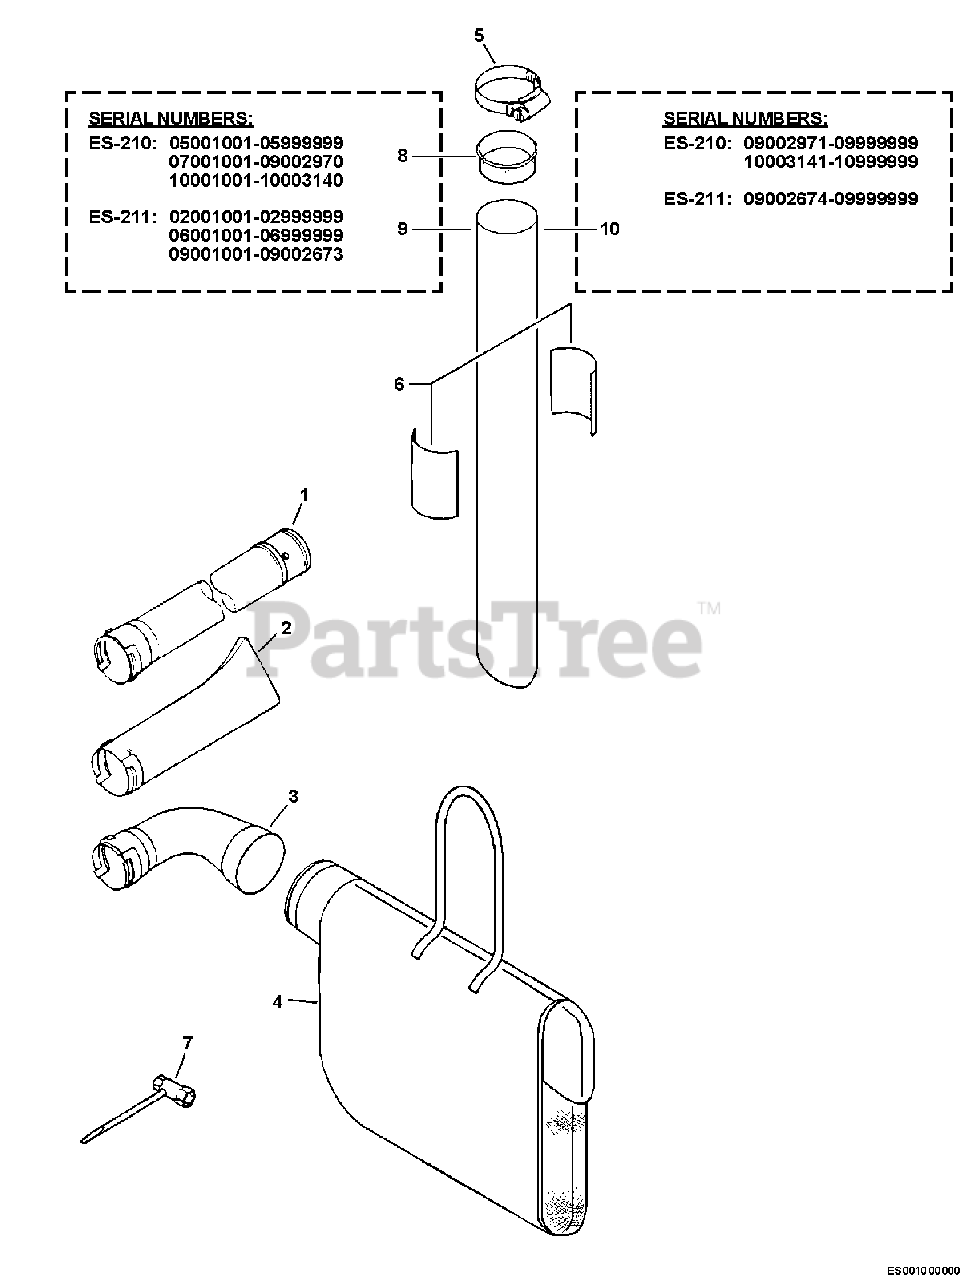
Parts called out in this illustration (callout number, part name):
1	TUBE, BLOWER - STRAIGHT
2	TUBE, BLOWER - NOZZLE
3	TUBE, DEBRIS
4	BAG, DEBRIS
6	LABEL - SHRED 'N' VAC
7	T-WRENCH - 13X19mm
9	TUBE, VACUUM
10	TUBE, VACUUM
